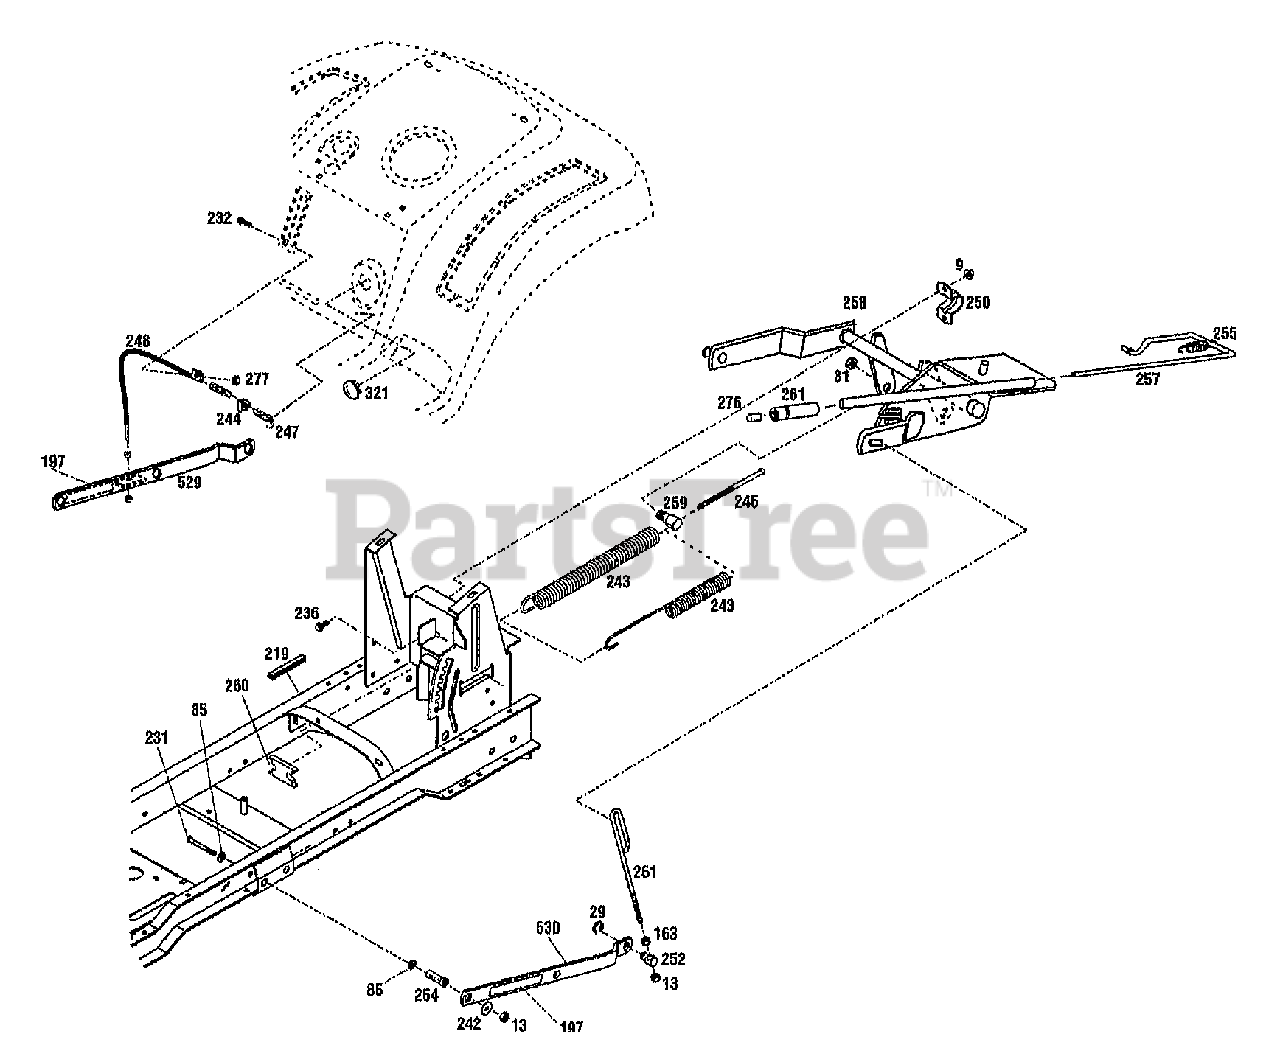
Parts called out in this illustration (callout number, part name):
9	NUT-HFLK 5/16-18 ZP
13	NUT-LOCK 3/8-16
29	RING-RETAINING
31	NUT-H/LK 5/8-11
85	WASHER-FLAT 3/8 SAE
163	NUT-HEX 3/8-16 ZP
197	DECAL-WARNING
231	SCR-HH 3/8-16X3.0 G5 ZP
232	SCR 10-24 X 5/8
236	SCR-HFLK 5/16-18X.75 ZP
242	WASHER-1.5X.375X.18 ZP
243	SPRING-LIFT ASSIST {13103}
243	SPRING-LIFT ASSIST {13104}
244	INDICATOR-HEIGHT
245	SCR-HH 3/8-16X5
247	SPRING-EXTENSION
248	ASSM-CABLE
250	CLAMP-LIFT
251	ROD-LIFT
252	SWIVEL-REAR LIFT
254	SPACER
255	SPRING-EXTENSION
258	ASSM-LIFT
259	BLOCK-PIVOT
260	SPRING-ANCHOR
261	GRIP-LIFT
276	BUTTON-LIFT
277	NUT-KEPS 10-24
321	PLUG-DOME
529	ASSM-RT LIFT LINK
530	ASSM-LT LIFT LINK
